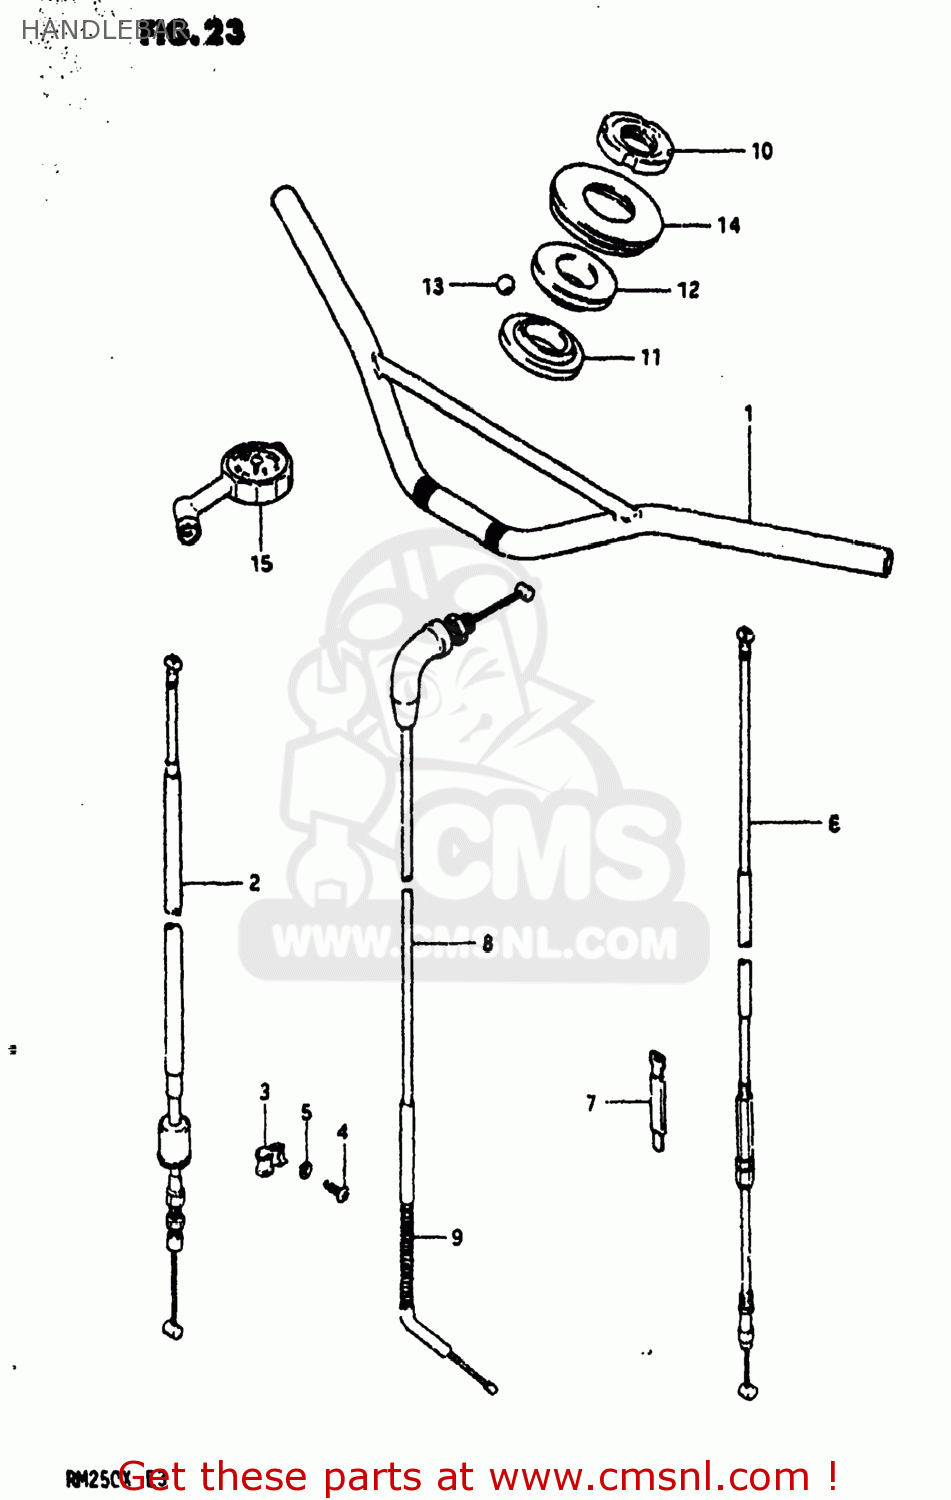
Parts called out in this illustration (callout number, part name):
1	HANDLEBAR
2	CABLE ASSEMBLY,FRONT BRAKE
3	GUIDE,CABLE
4	SCREW
5	LOCK WASHER
6	CABLE ASSEMBLY,CLUTCH
7	CLAMP
8	CABLE ASSEMBLY,THROTTLE
9	PROTECTOR,CABLE
10	NUT,STEERING STEM
11	RACE,STEERING,INNER,UPPER
12	RACE,STEERING,OUTER,UPPER
13	BALL
14	SEAL,STEERING UPR DUST
15	GAUGE ASSY,AIR PRESSURE
